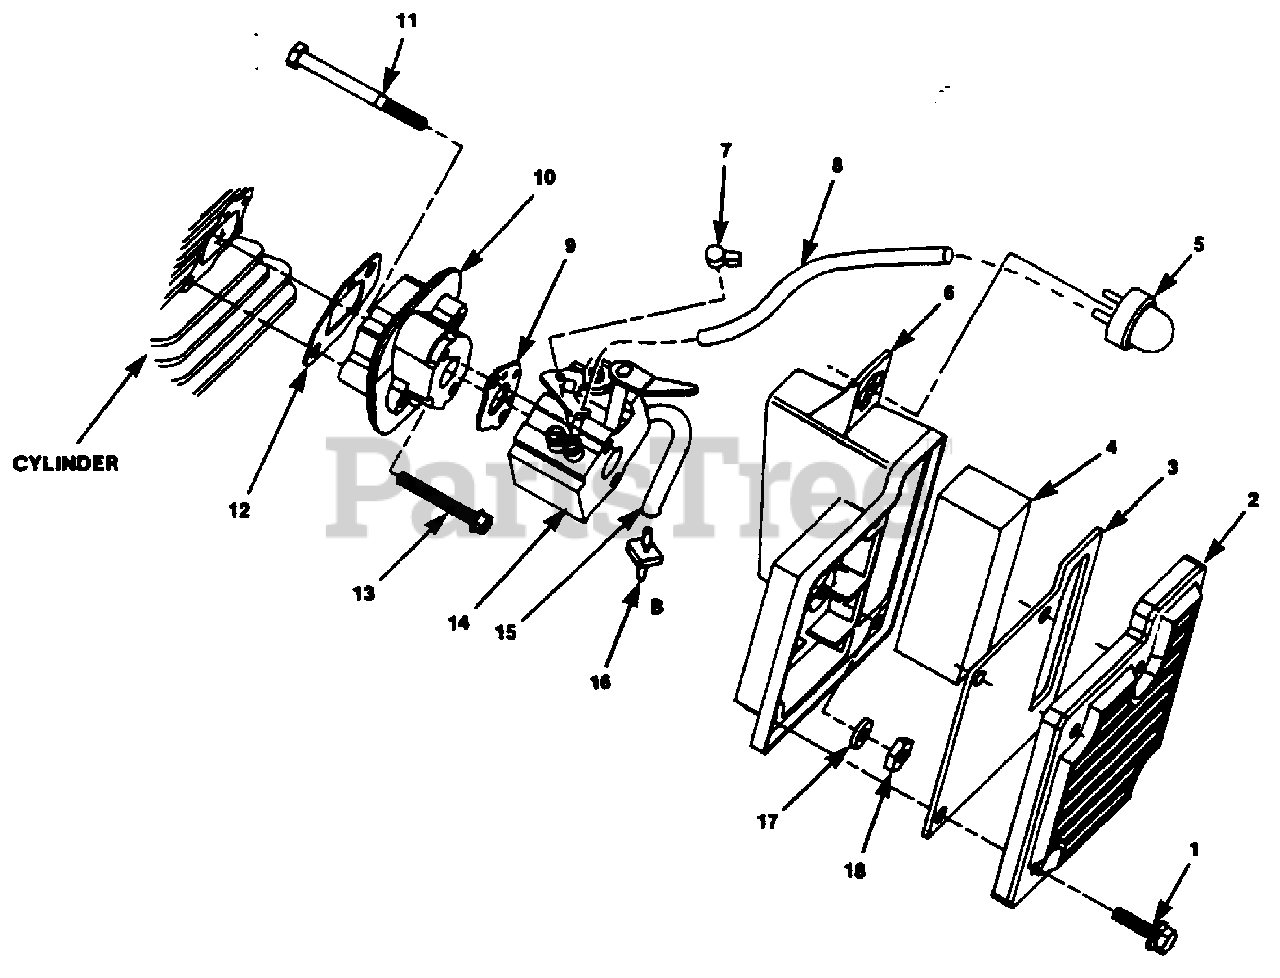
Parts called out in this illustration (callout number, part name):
1	SCREW- Sems hex hd (1/4-20 x 7/8")
2	COVER- Air filter
3	FILTER- Felt air
4	FILTER- Foam air
5	BULB- Primer
6	AIR FILTER BOX
7	CAP- Limit (HBC-40)
8	TUBING- Rubber (5")
10	SPACER- Carburetor
11	BOLT- Carburetor mtg. (8-32 x 2")
12	GASKET- Carburetor spacer
13	SCREW- Carb. spacer (8-32 x 1 1/4")
14	CARBURETOR (Zama) (HBC-40)
15	TUBING- Rubber
16	FITTING- Fuel inline
17	WASHER- Flat
